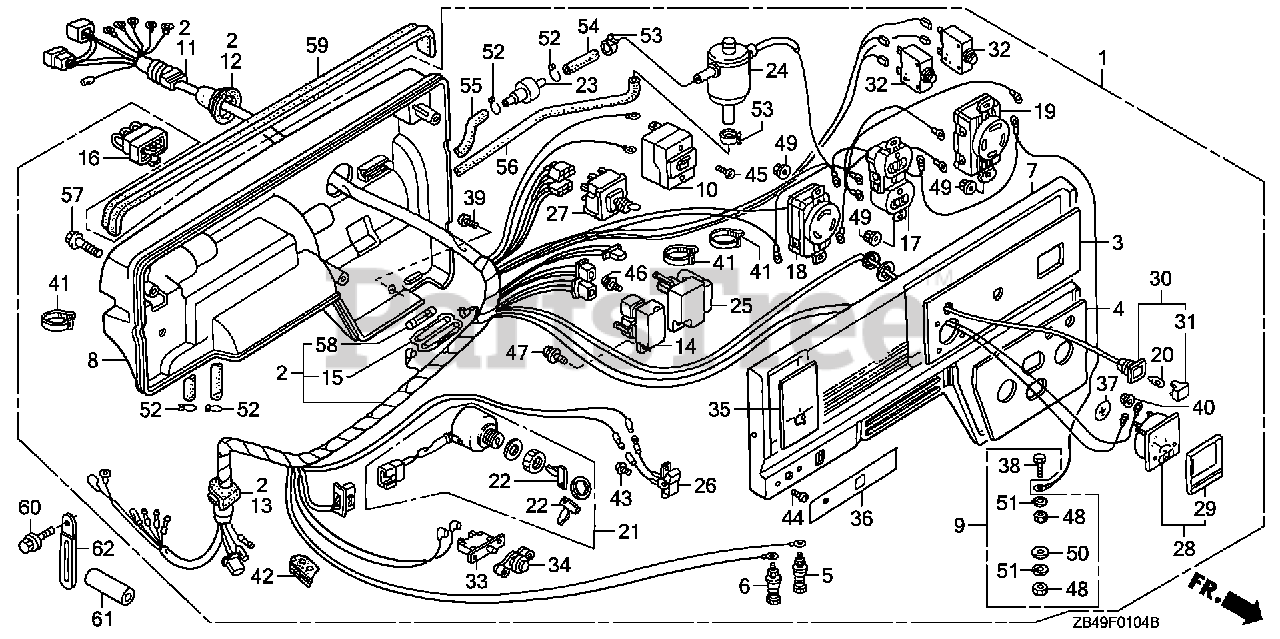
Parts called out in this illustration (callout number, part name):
1	BOX ASSY., CONTROL *R8* (BRIGHT RED)
1	BOX ASSY., CONTROL *R280* (POWER RED)
2	WIRE HARNESS ASSY. (NOT AVAILABLE)
3	MARK, SWITCH PANEL
4	MARK, A.C. OUT
5	TERMINAL, D.C. OUTPUT (+)
6	TERMINAL, D.C. OUTPUT (-)
7	PANEL, CONTROL *R280* (POWER RED)
8	CASE, CONTROL *R280* (POWER RED)
9	TERMINAL SET, GROUND
10	BREAKER, CIRCUIT (14A)
11	GROMMET, A.C. WIRE
12	GROMMET, MAIN WIRE
13	GROMMET, SWITCH WIRE
14	DIODE ASSY.
15	CASE, FUSE CONNECTOR (SUMITOMO)
16	CONNECTOR ASSY.
17	RECEPTACLE (20A/125V)
18	RECEPTACLE (30A/125V)
19	RECEPTACLE (20A-125/250V) (MATSUSHITA) (NOT AVAILABLE)
20	BULB, WEDGE BASE (12V/2W)
21	SWITCH ASSY., COMBINATION
21	SWITCH ASSY., COMBINATION (HONDALOCK)
22	KEY (HONDALOCK)
23	VALVE, DASHPOT CHECK
24	VALVE ASSY., SOLENOID
25	THROTTLE UNIT, AUTO (SAWAFUJI)
26	SWITCH, AUTO THROTTLE
27	SWITCH ASSY., VOLT CHANGE
28	METER ASSY., VOLT (300V)
29	LENS, METER
30	SOCKET ASSY., LAMP (GREEN)
31	LENS (GREEN)
32	PROTECTOR, CIRCUIT (20A)
33	PROTECTOR, CIRCUIT (D.C.)
34	LENS ASSY., PROTECTOR
35	MARK, ENGINE SWITCH
36	MARK, D.C. OUT
37	MARK, GROUND
38	BOLT, HEX. (6X28)
39	SCREW, GLOVE BOX
40	NUT, FLANGE (3MM)
41	TIE, CABLE (NATURAL 225X5.0)
42	GROMMET, TUBE
43	SCREW, PAN (3X6)
44	SCREW, PAN (3X12)
45	SCREW, PAN (4X6)
46	SCREW-WASHER (5X12)
47	SCREW-WASHER (4X12)
48	NUT, HEX. (6MM)
49	NUT, FLANGE (4MM)
50	WASHER, PLAIN (6MM)
51	WASHER, SPRING (6MM)
52	CLIP, TUBE (B7)
53	CLAMP, TUBE (D8)
54	BULK HOSE, VACUUM (3.5X8000) (3.5X30)
55	BULK HOSE, VACUUM (3.5X8000) (95005-35001-10M(95005-35001-1
56	BULK HOSE, VACUUM (3.5X8000) (95005-35001-10M(95005-35001-1
57	BOLT, FLANGE (6X40)
58	FUSE B (10A)
59	RUBBER, CONTROL
60	BOLT, FLANGE (6X12) (CT200)
61	TUBE, CORD
62	CLIP, WIRE HARNESS
